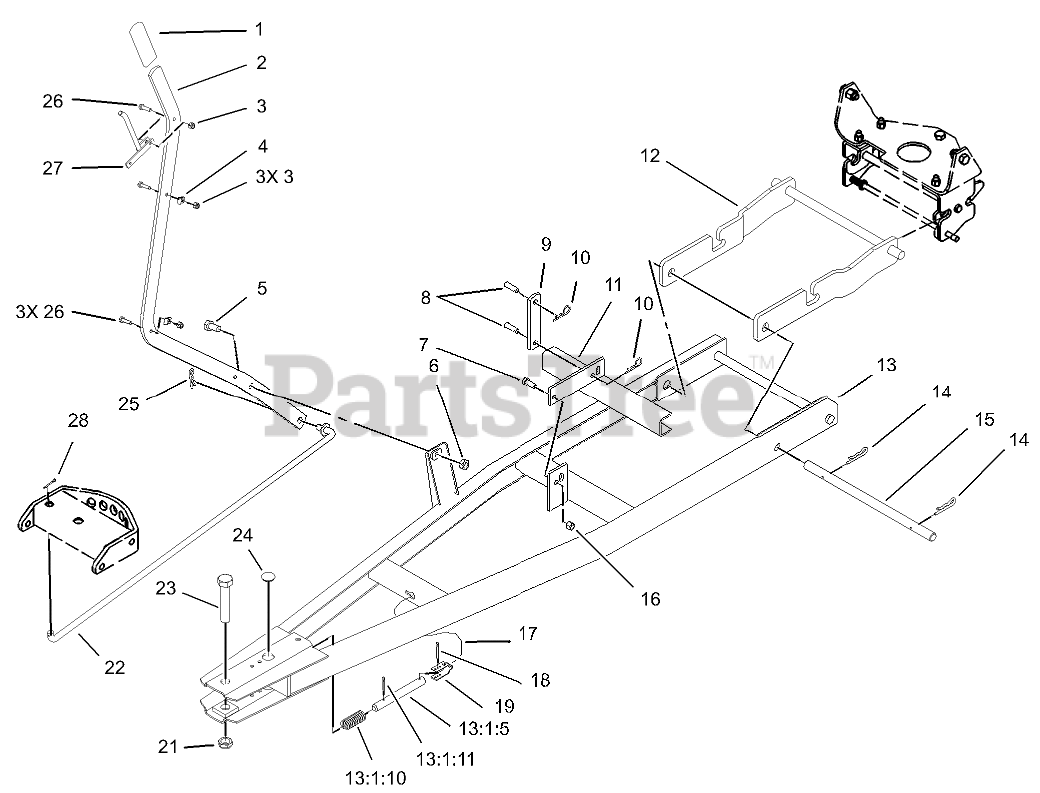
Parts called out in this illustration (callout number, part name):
1	GRIP
2	LEVER-BLADE
3	NUT-LOCK
4	R-CLAMP
5	SCREW-HH
6	NUT-JAM
7	SCREW-HH
8	PIN-CLEVIS
9	LINK-LIFT
10	PIN-HAIR
11	Lift ASM
12	DOZER EXTENSION ASM
13:1:5	PIN-INDEX
13:1:10	SPRING-COMPRESSION
13:1:11	PIN-COTTER
14	PIN-HAIR
15	SHAFT
16	NUT-LOCK, NI
17	CABLE-TENSION
18	PIN-COTTER
19	BRACKET - CABLE END
21	NUT-LOCK
23	SCREW-HH
24	PLUG
25	PIN-HAIR
26	SCREW-HH
27	LEVER-INDEX
28	PIN-COTTER
